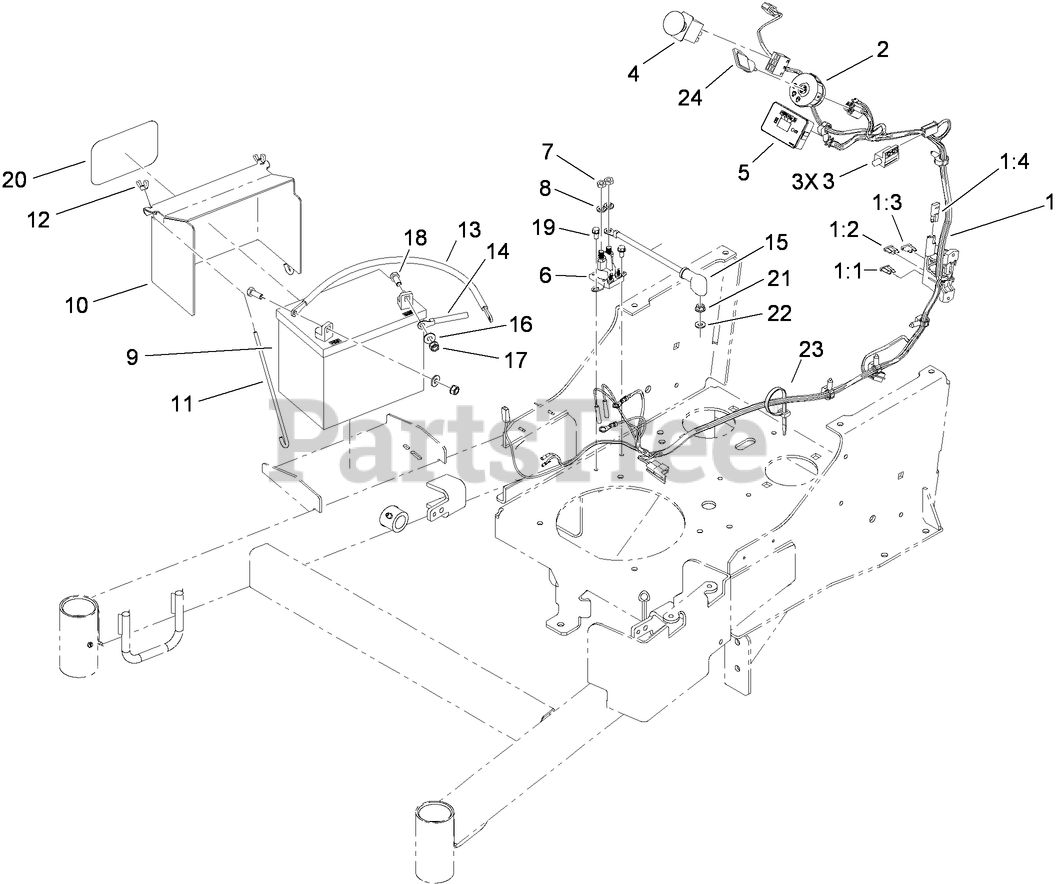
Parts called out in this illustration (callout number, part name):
1	HARNESS-WIRE
1:1	FUSE-BLADE, 30 AMP
1:2	FUSE-BLADE, 25 AMP
1:3	FUSE-BLADE, 10 AMP
1:4	CAP-PLUG
2	SWITCH-IGNITION
3	SWITCH-CLOSED, NORMALLY
4	SWITCH-PTO, ON-ON-(ON)
5	MODULE-METER, HOUR
6	SWITCH-SOLENOID
7	NUT-JAM
8	WASHER-LOCK
9	BATTERY
10	COVER-BATTERY
11	BOLT-HOLDDOWN
12	WINGNUT
13	CABLE-BATTERY, POSITIVE
14	CABLE-BATTERY, BLACK
15	CABLE-BATTERY, RED
16	WASHER-PLAIN
17	NUT-HHF, SMOOTH
18	SCREW-HH
19	SCREW-HWH
20	DECAL
21	WASHER-FLAT
22	NUT-HF
23	TIE-CABLE
24	KEY-IGNITION
